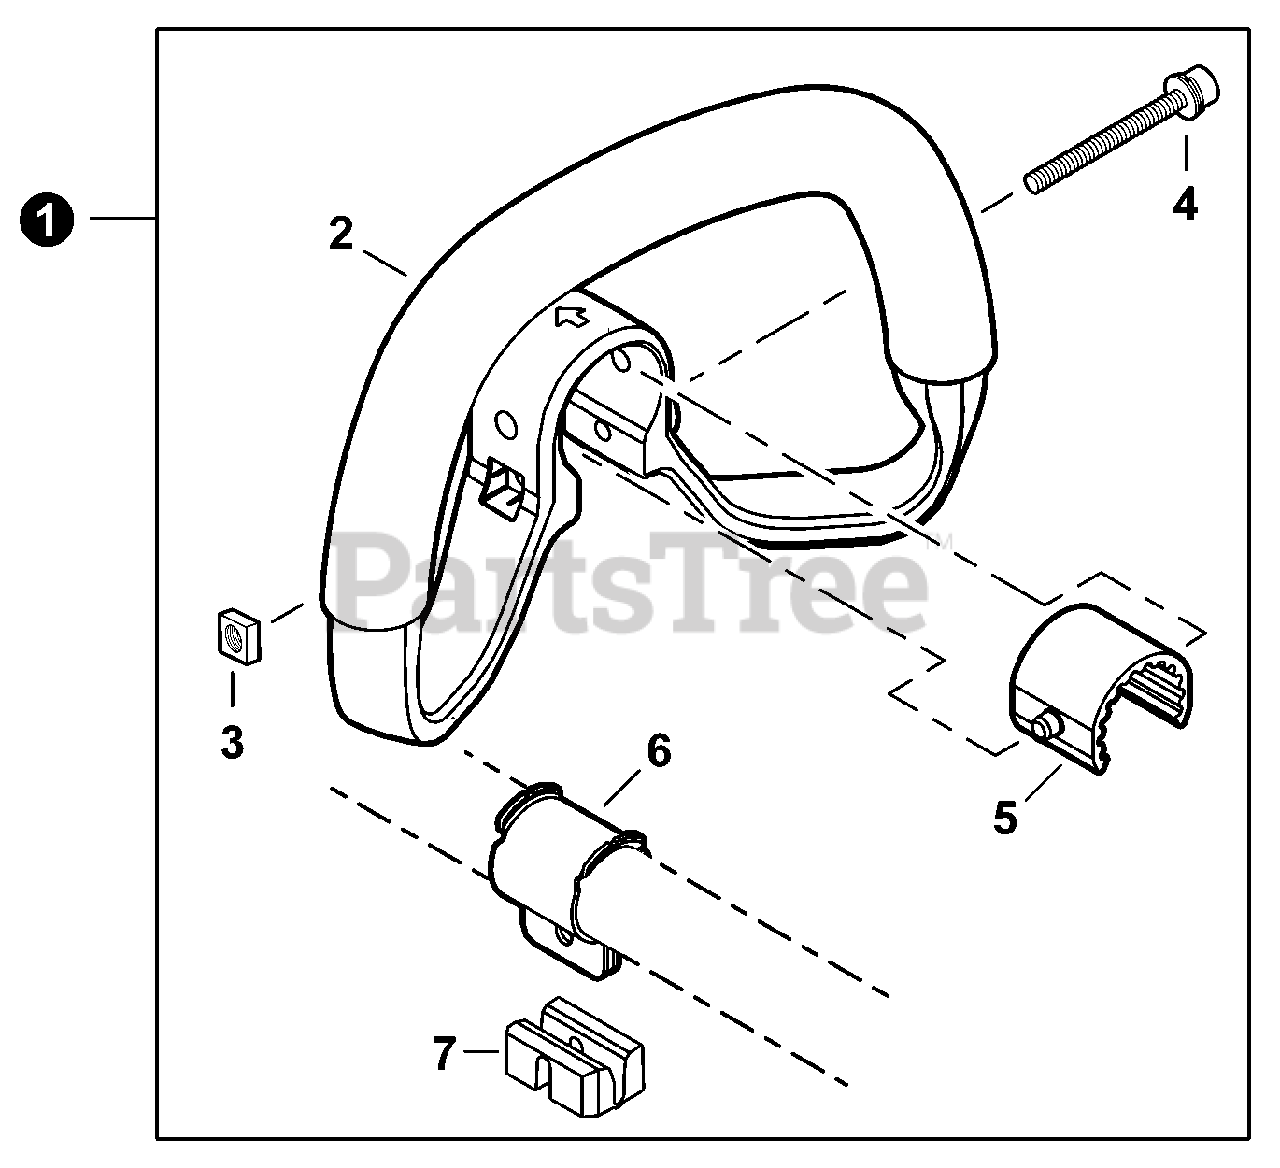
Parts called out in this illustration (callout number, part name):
1	HANDLE ASSY - SUPPORT
2	HANDLE, SUPPORT
4	BOLT 5×45
5	CUSHION
6	BRACKET, MOUNTING
